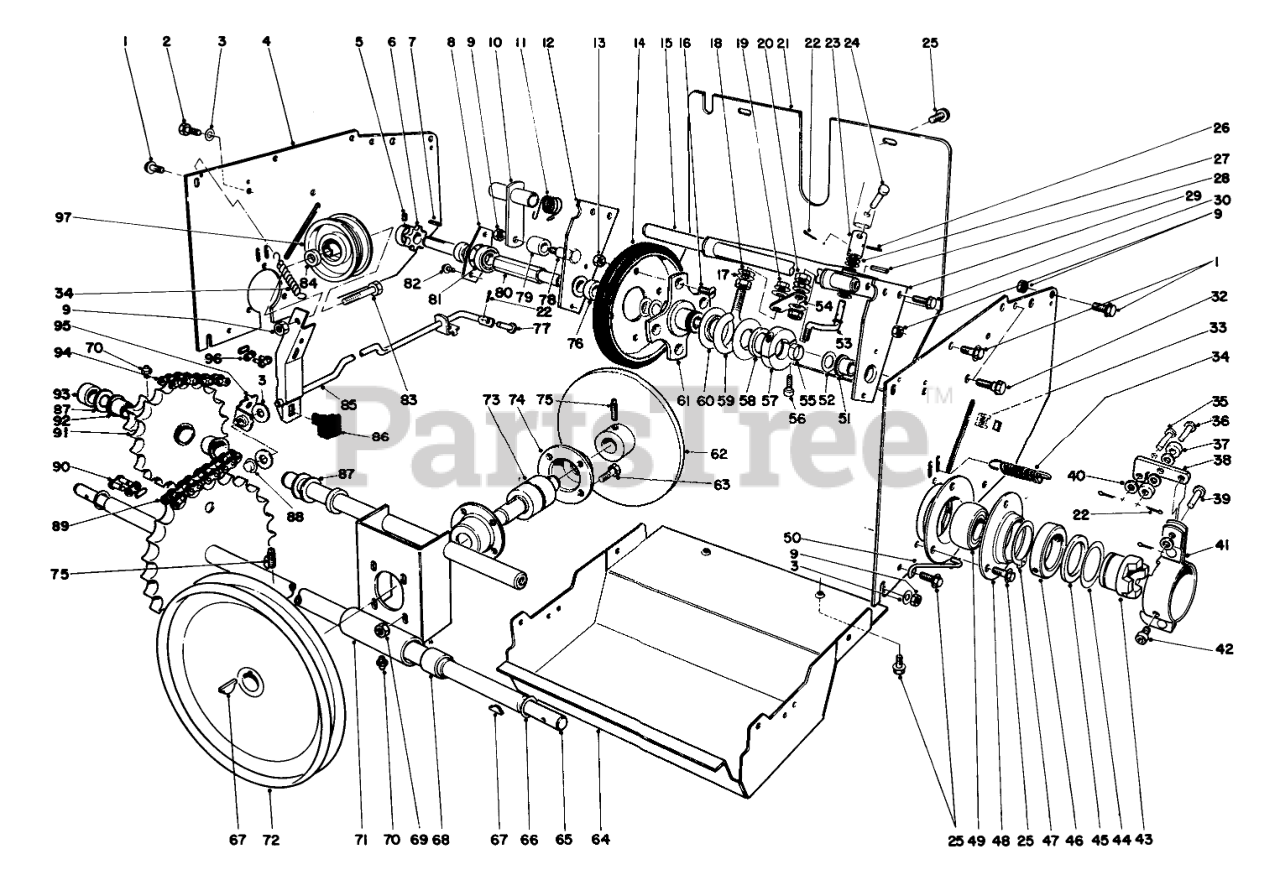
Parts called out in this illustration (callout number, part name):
1	SCREW-HH
2	SCREW-HHFTF
3	WASHER-FLAT
4	Side Plate Drive
5	SCREW-HSH
6	SPROCKET
8	BEARING CUP
9	NUT-HEX
10	CHAIN TENSION ARM WA
11	TORSION SPRING
12	HEX SHAFT MOUNT R
13	Nut
14	FRICTION WHEEL
15	Bracket Dead Shaft
16	5/16-18X5/8 FLT HD MS
17	WASHER-FLAT
18	WASHER-SPRING
19	NUT-LOCK, FLANGE
20	Nut
21	REAR COVER R
22	PIN-COTTER
23	U JOINT TUBE
24	CLEVIS PIN
25	SCREW-HWH
26	PIN-SPRING
27	Clevis Pin
28	PIN-ROLL
29	HEX SHF MNT & BSHG AS
30	SCREW-HWHTF
32	SHOULDER SCREW
33	Retained Nut
34	EXTENSION SPRING
35	PIN-CLEVIS
36	PIN-CLEVIS
37	CLUTCH ROLLER
38	CLUTCH CAM ARM
39	PIN-CLEVIS
40	WASHER-FLAT
41	CLUTCH MT BRKT ASM
42	Hex Socket Capscrew
43	WHEEL CLUTCH
44	THRUST WASHER
45	THRUST BEARING
46	CLUTCH MOUNT COLLAR
47	RING-RETAINING, EXTERNAL
48	BEARING FLANGE
49	BEARING
50	CLUTCH RETAINER
51	BUSHING
52	WASHER-FLAT
53	CONNECTION ROD
54	SHIFT ROD PIVOT
55	SPLIT SPACER
56	SCREW-HSH
57	ColIar
58	WASHER-THRUST
59	SLIDER RING COLLAR
60	SLIDER RING
61	TRACTION DISC HUB
62	FRICTION PLATE O
63	SCREW-HH
64	LOWER SHIELD R
65	AXLE SHAFT WA
66	WASHER
67	KEY-WOODRUFF
68	BUSHING
69	NUT-KEPS
70	FITTING-GREASE
71	Bulkhead (Incl. Ref. #68)
72	Pulley
73	BEARING-FRICTION PLATE
74	HOUSING BEARING
75	SCREW-SET, SQH
76	SPACER
77	PIN-CLEVIS
78	SHOULDER BOLT
79	CHAIN TENSION ROLLER
80	FRICTION WHEEL SHAFT
81	BEARING
82	SCREW
83	SCREW-HH
84	Spacer
85	Auger Brake Assembly (Incl. Ref. #86)
86	Brake Pad
87	WASHER-THRUST
88	PUSH NUT
89	ROLLER CHAIN
90	LINK-CHAIN
91	Sprocket (Incl. Ref. #98)
92	3/4ID X 3/4LG BSHG
93	SPACER-IDLER
94	1/4 X 42 CHAIN W/LINK
95	Bracket-Clutch
96	LINK-CONNECTING
97	PULLEY-IDLER
